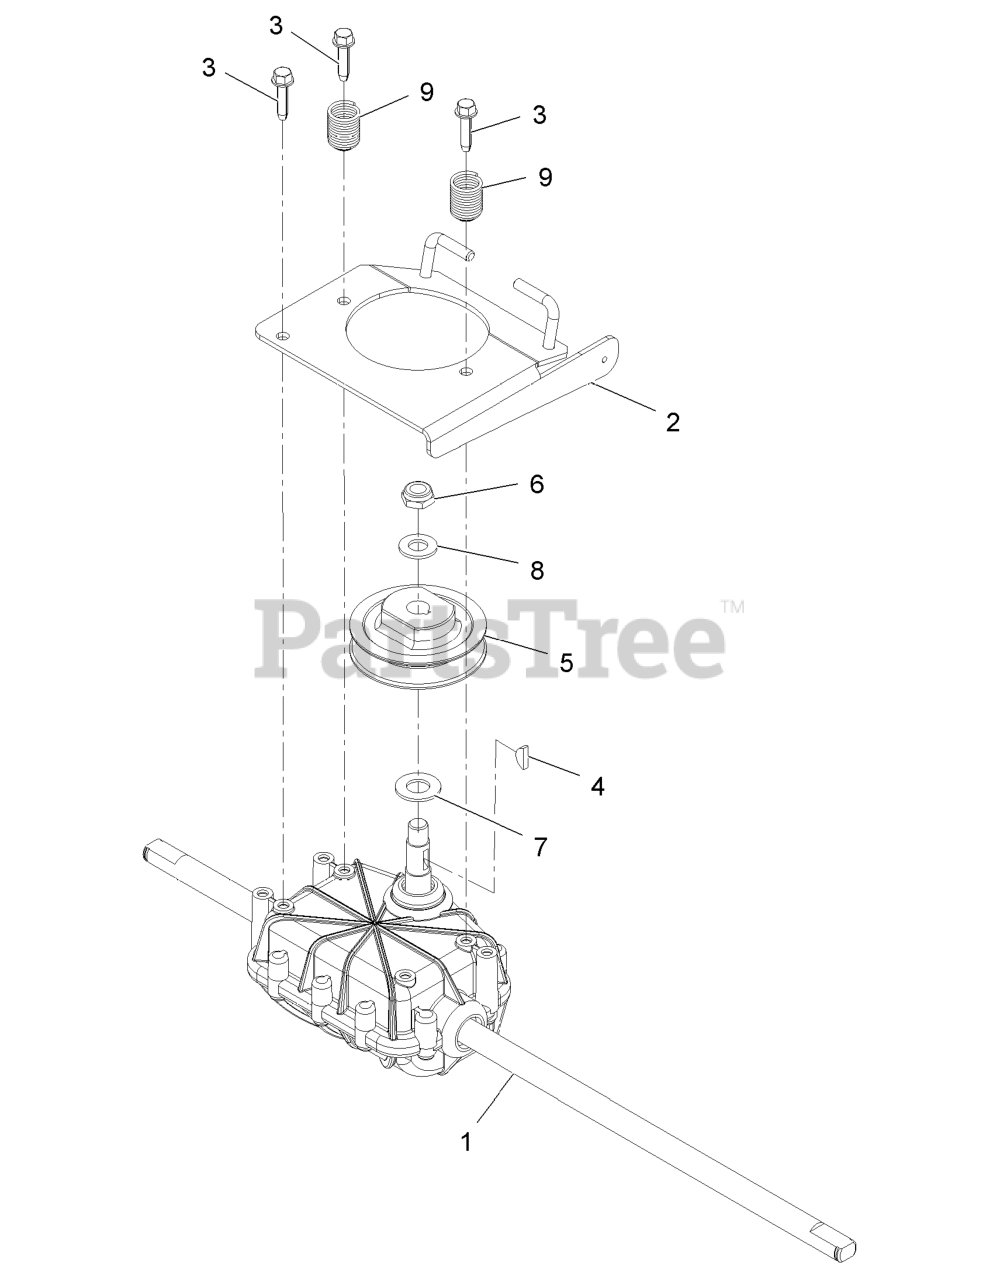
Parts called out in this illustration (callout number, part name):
2	TRANSMISSION PLATE ASM
3	SCREW-SPECIAL
4	KEY-WOODRUFF
6	NUT-HEX
7	WASHER-THRUST
8	WASHER-FLAT
9	SPRING,COMPRESSION
